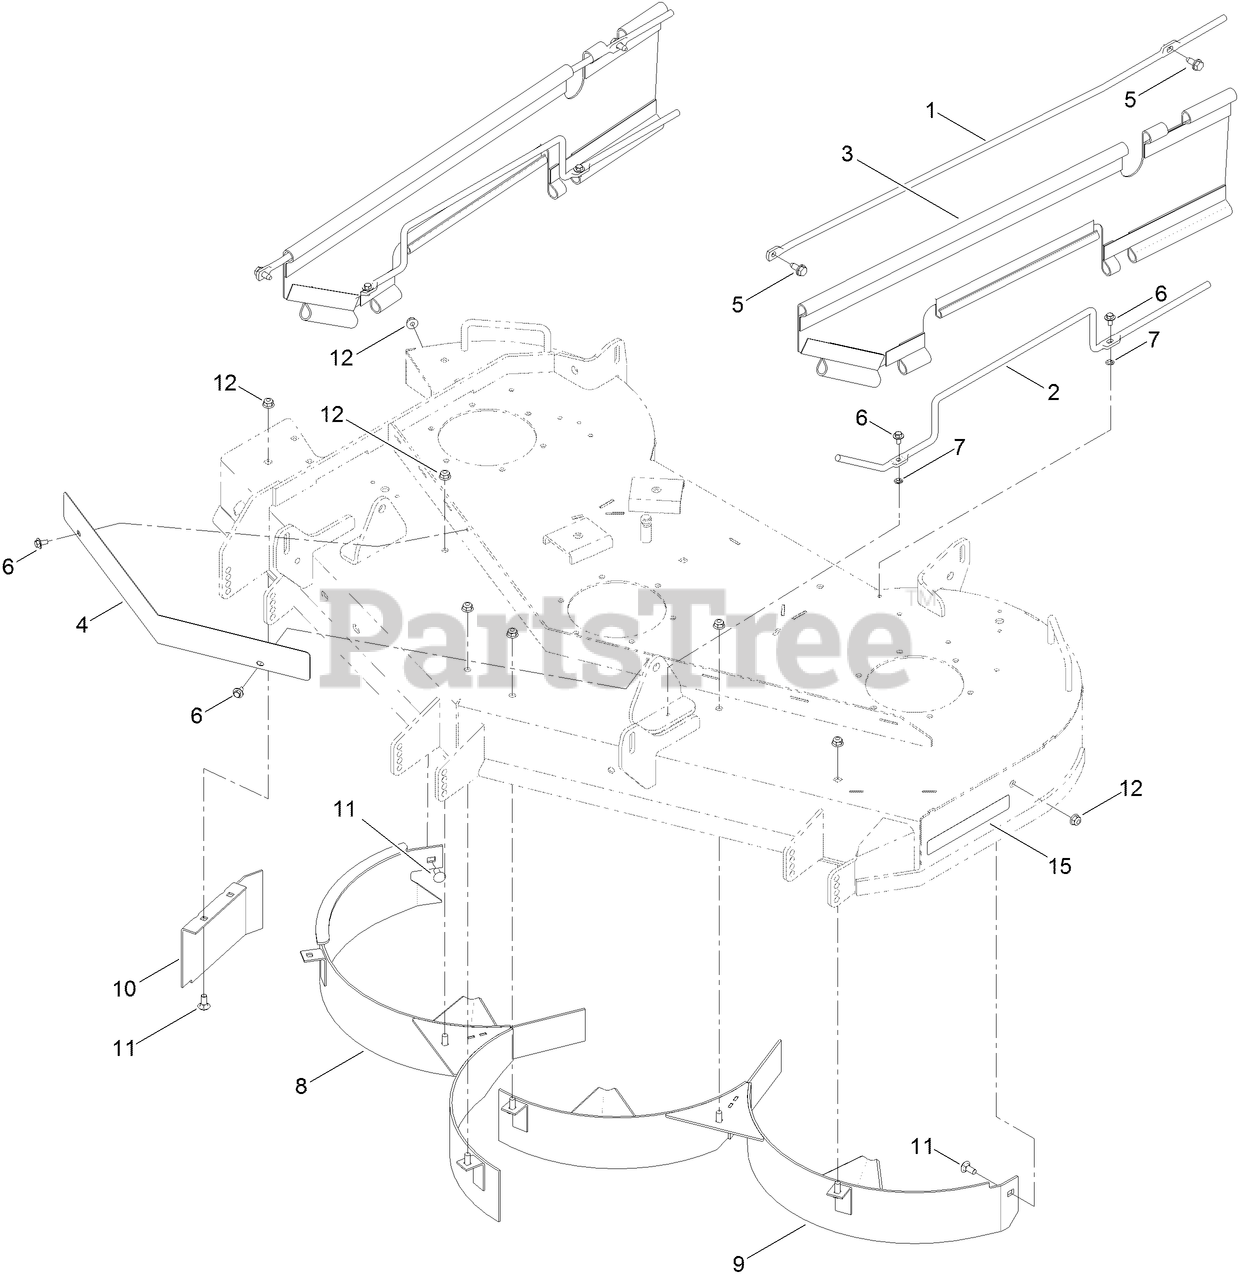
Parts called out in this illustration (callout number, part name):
1	ROD SUPPORT, UPPER
2	ROD SUPPORT, LOWER
3	GUARD-SIDE
4	SHIELD-FRONT
5	SCREW-HWHTF
6	SCREW-HHFTF
7	NUT-RETAINING
8	BAFFLE-RECYCLER, RH
9	BAFFLE-RECYCLER, LH
10	GUARD-BAFFLE
11	BOLT-CARR
12	NUT-HF, NI
15	DECAL-RECYCLER
